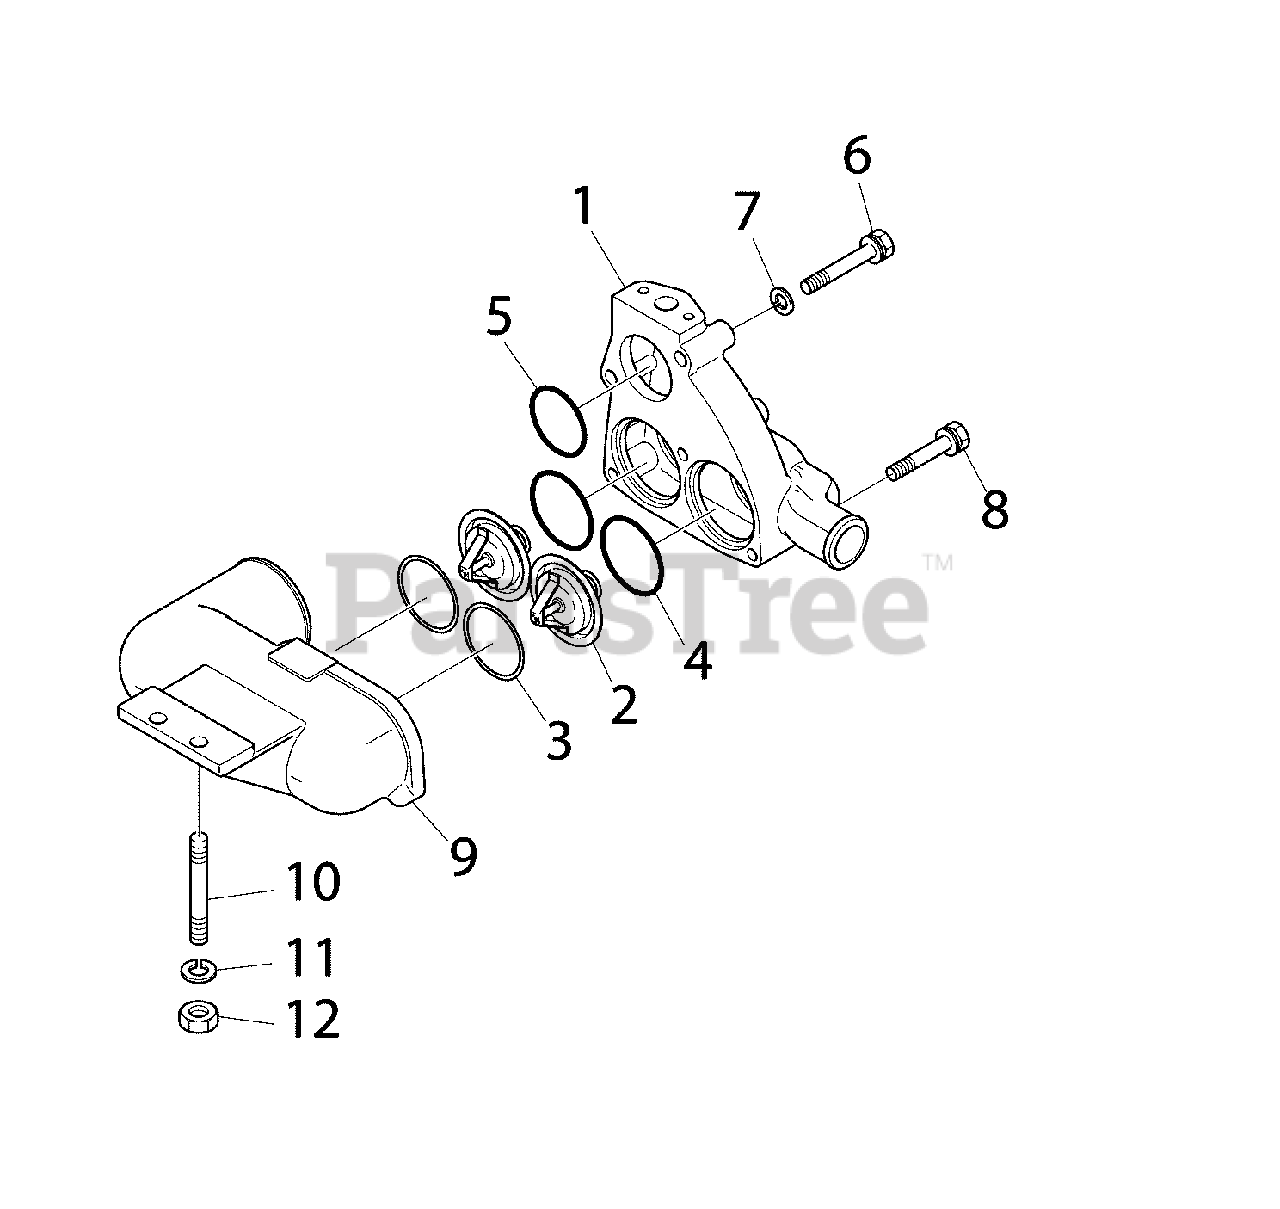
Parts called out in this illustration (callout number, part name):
1	* HOUSING, THERMOSTAT
2	THERMOSTAT (STD 160 DEG)
2	* THERMOSTAT (174 DEG)
2	* THERMOSTAT (181 DEG)
3	GASKET, THERMOSTAT
4	O-RING
5	O-RING
6	* BOLT
7	* WASHER
8	* BOLT
9	* HOUSING, THERMOSTAT
10	* BOLT, STUD
11	* WASHER, SPRING
12	* NUT, HEX
